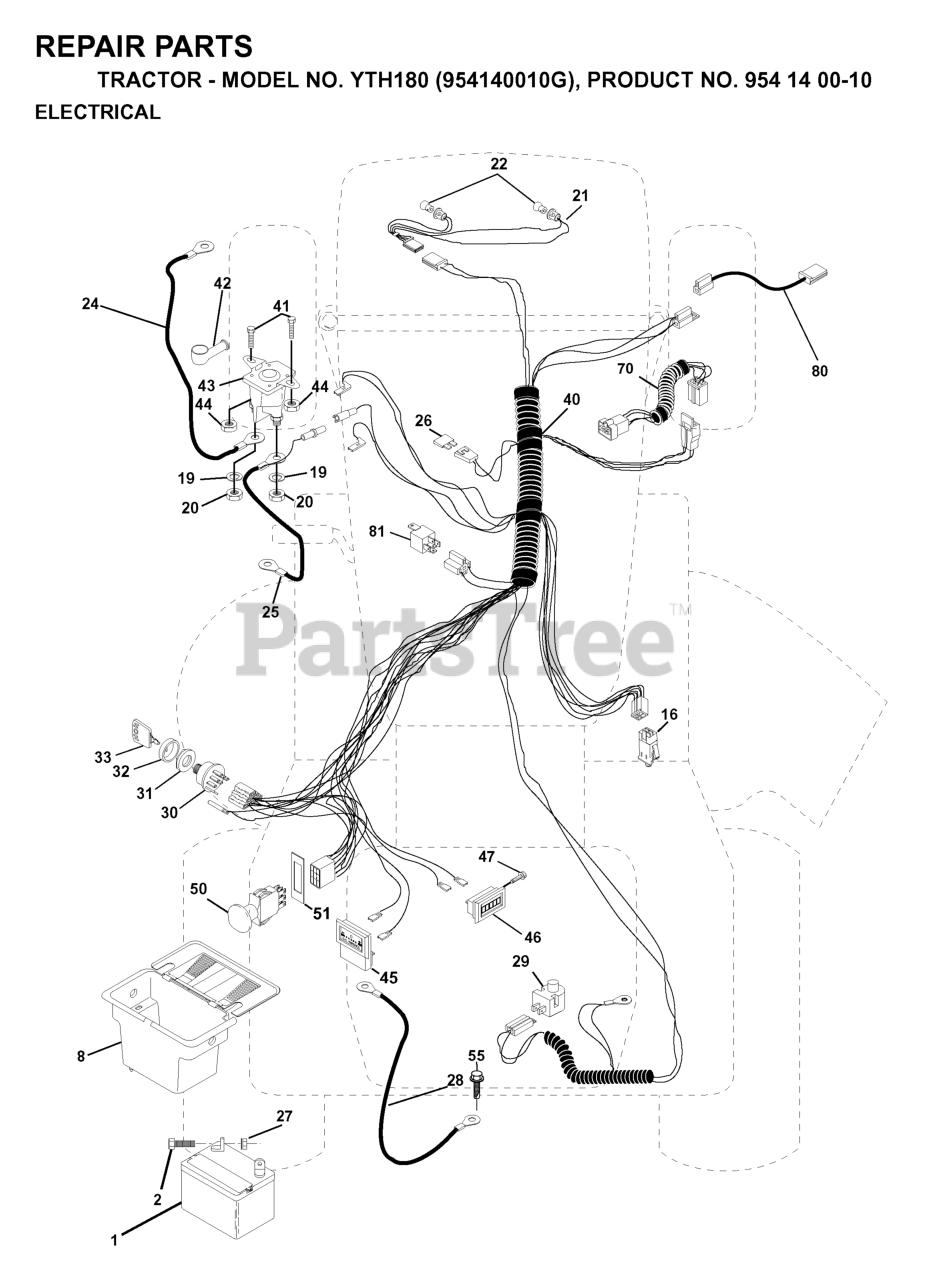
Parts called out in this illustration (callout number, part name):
1	BATTERY 12V .35 AMP
2	BOLT.HEX.1/4.X.3/4.DICHROMATE
8	BATTERY TRAY T
10	BOLT 1/4-20 X 7.5
11	BATTERY HOLDDOWN FRONT MOUNT
12	NUT, PUSH NYLON 1/4" BATTERY
16	SWITCH INTERLOCK
19	LOCKWASHER
20	NUT
21	HARNESS LIGHT SOCKET
24	BATTERY CABLE GT
25	CABLE BATTERY 6 GA 22" W/16W
27	NUT
28	CABLE GROUND 6 GA 21" 90T BLK
29	PLUNGER SWITCH (COLOR:OLIVE)
30	SWITCH.IGNITION.4.POSITION
31	NUT IGNITION
32	COVER SWITCH KEY
33	KEY.MOLDED.GENERIC
40	WIRING HARNESS
41	BOLT
42	TERMINAL COVER
43	SOLINOID
44	Nut, Keps Blk Hex 1/4-20 UNC
46	HOUR METER T
47	Screw 10-24 x 1/2 Black
50	SWITCH PTO 3 PDT
51	FRAME RETAINING RING
55	Screw 5/16-18 x 1/2 Hex, Self Tapping 5/16-18 x 1/2
80	HARNESS, CLUTCH
81	RELAY.ASSY.T
